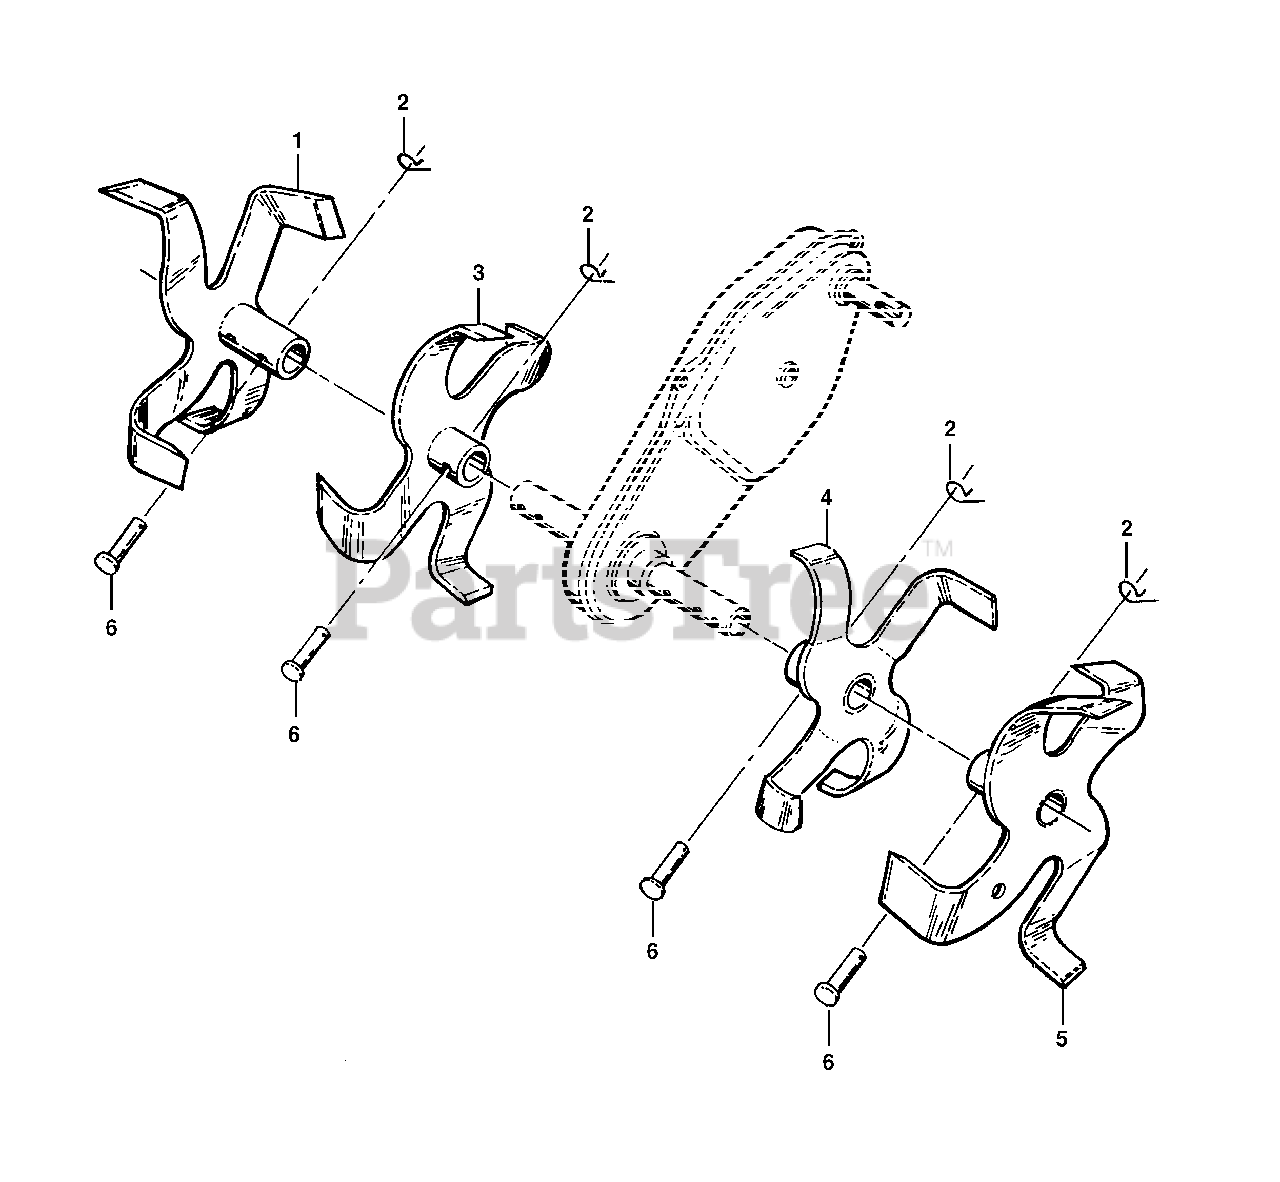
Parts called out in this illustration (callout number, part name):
1	Tine, Outer, R.H.
2	Retainer, Spring
3	Tine, Inner, R.H.
4	Tine, Inner, L.H.
5	Tine, Outer, L.H.
6	Pin, Clevis
